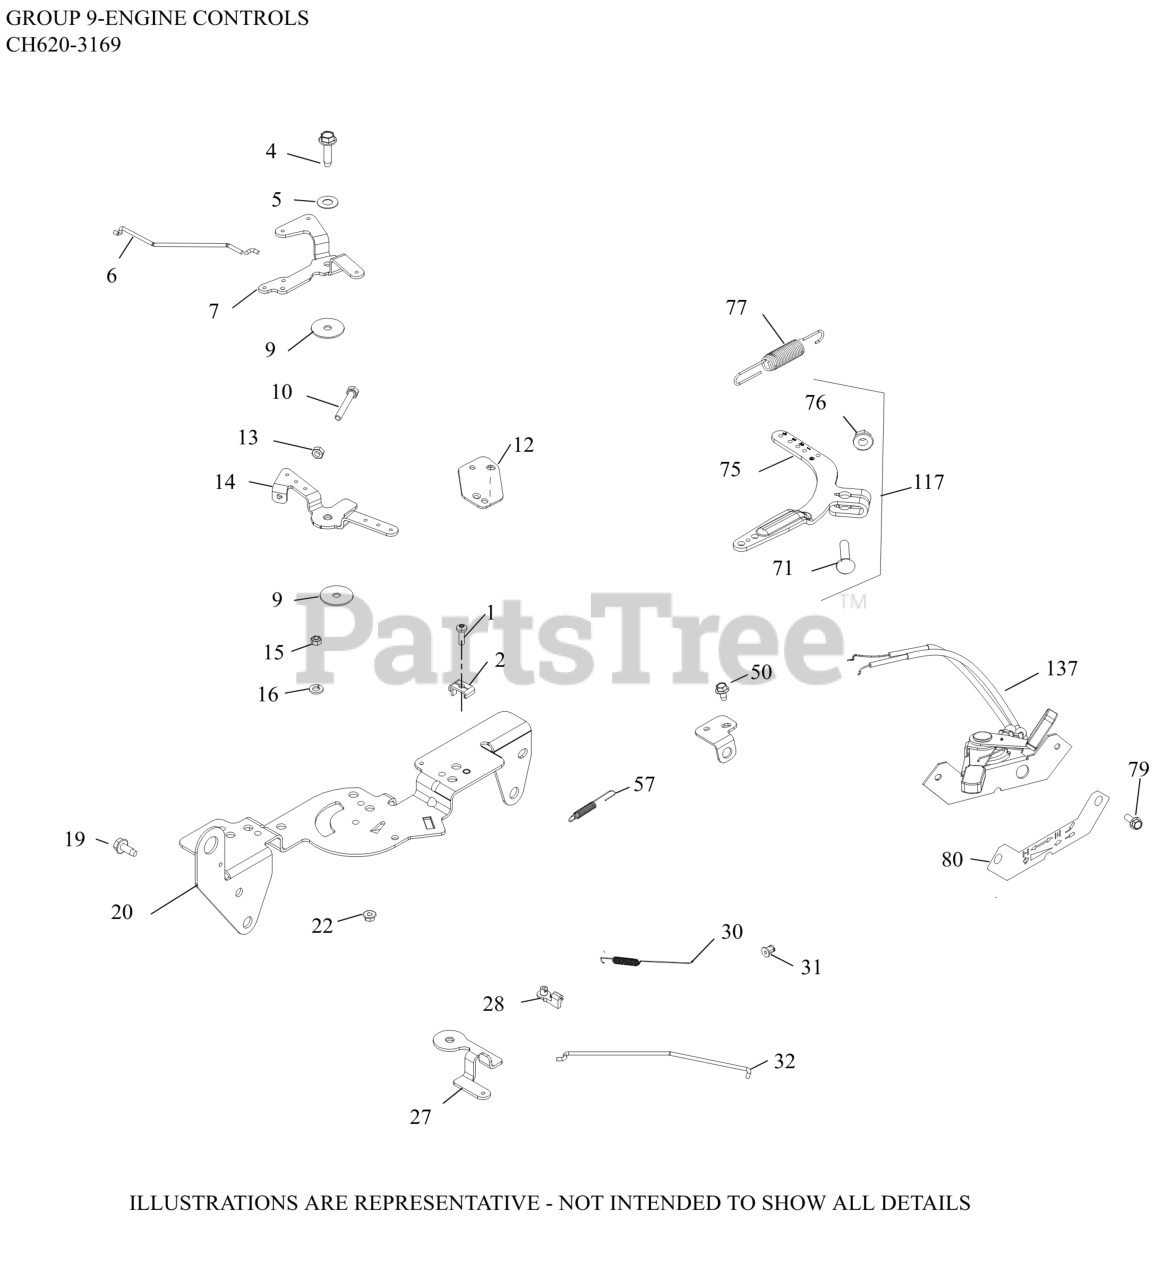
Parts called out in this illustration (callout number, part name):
1	SCREW, THREAD FORMING
2	CLAMP, CABLE CABLE
4	SCREW, THD FRM-USE 25 086 473-S
5	WASHER, SPRING 1/4"
6	LINKAGE, CHOKE
7	LEVER, CHOKE
9	WASHER, FLAT 5.5 MM
10	SCREW, CAP M4X.7X30
12	BRACKET, CABLE SUPPORT
13	NUT, M4X0.7
14	LEVER, THROTTLE CONTROL
15	NUT, FLG M5X.8
16	WASHER, SPRING LOCK 1/4"
19	SCREW, THREAD FORMING
20	BRACKET, CONTROL
22	NUT, LOCK M5X.8
27	LEVER, THROTTLE ACTUATOR
28	BUSHING, THROTTLE LINKAGE
30	SPRING, LINKAGE
31	BUSHING, LINKAGE RETAINING
32	LINKAGE, THROTTLE
50	SCREW, THREAD FORMING
57	SPRING, THROTTLE LIMITER
71	BOLT, RD HD SQ NECK M6X1.0X25
75	LEVER, GOVERNOR - (#2409069S)
76	NUT, FLG M6X1.0
77	SPRING, GOVERNOR (BLUE)
79	SCREW, HI-LOW
80	DECAL, CONTROL PANEL
117	LEVER, GOVERNOR ASSEMBLY
137	CABLE, CONTROL ASSEMBLY
